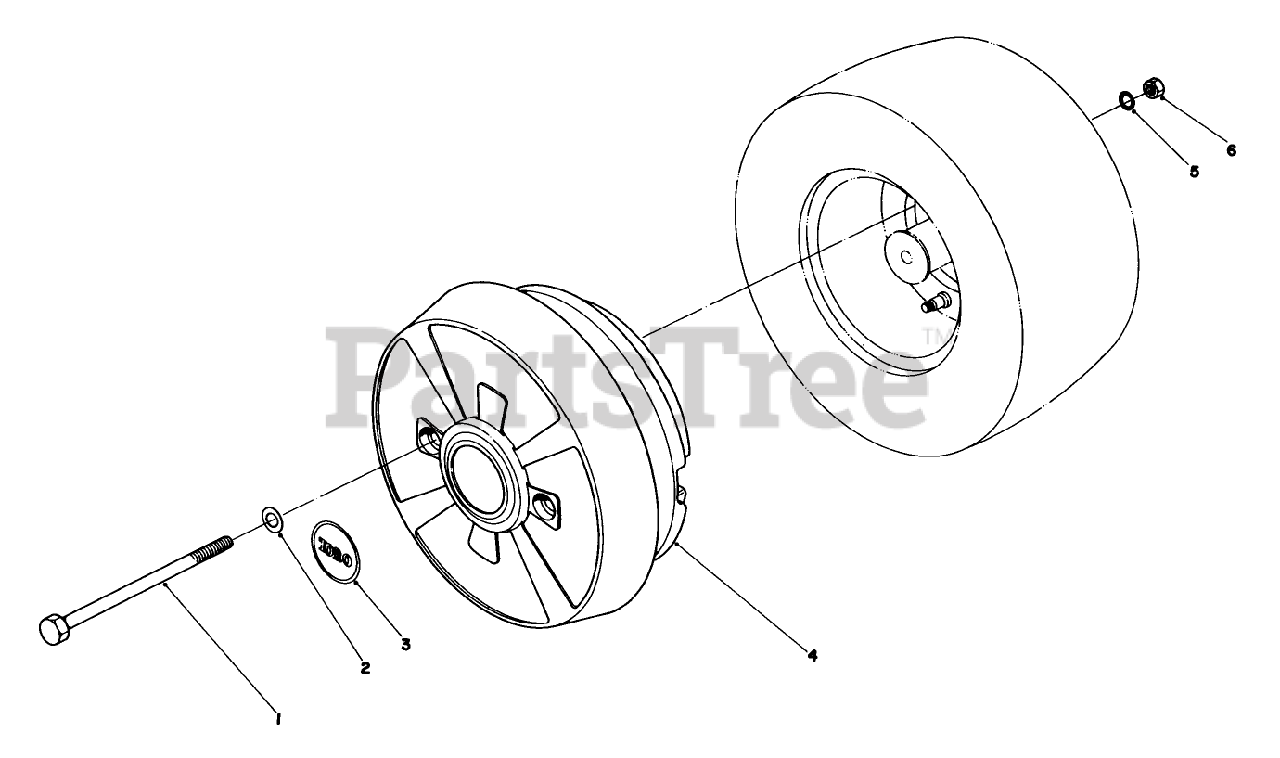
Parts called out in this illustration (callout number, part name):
1	Capscrew
2	Flatwasher
4	Wheel Weight
5	Lockwasher
6	Hex Nut
